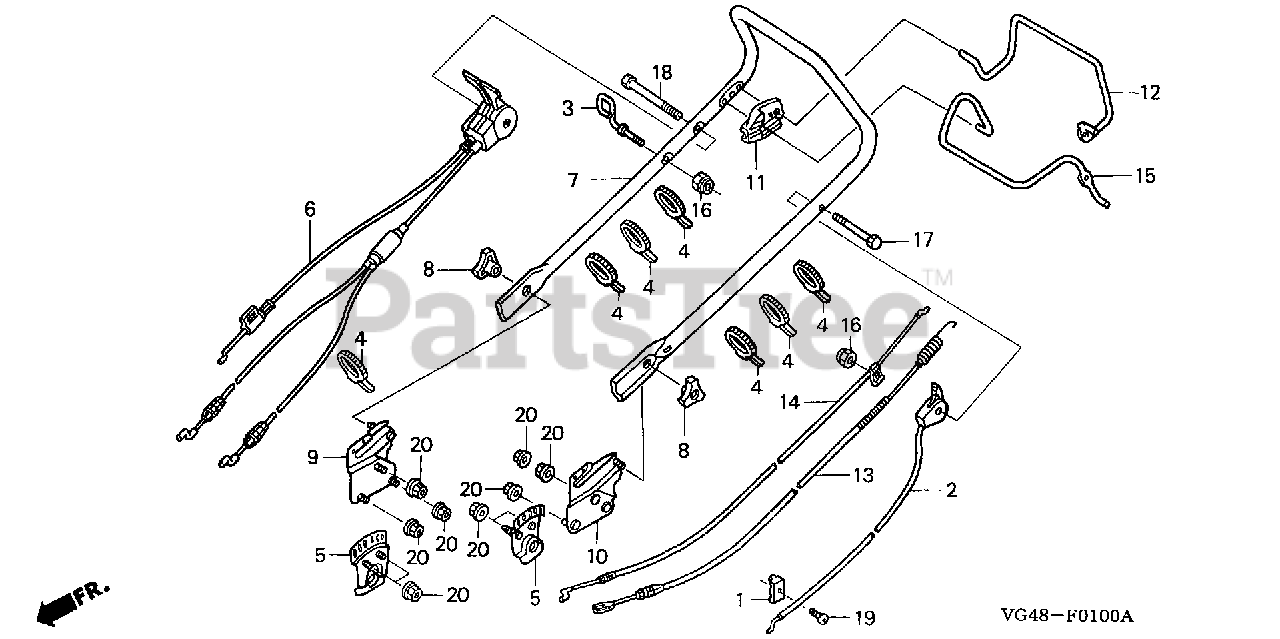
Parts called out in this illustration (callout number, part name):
1	HOLDER, CABLE
2	LEVER ASSY., THROTTLE
3	GUIDE, ROPE
4	TIE, CABLE (157.5MM)
5	PANEL, RR. ADJUSTER
6	CABLE, CASTER
7	PIPE, HANDLE *NH105* (MAT BLACK)
8	GRIP, HANDLE JOINT
9	STAY, R. HANDLE
10	STAY, L. HANDLE
11	STOPPER, LEVER
12	LEVER, CLUTCH
13	CABLE, CLUTCH
14	CABLE, BRAKE
15	LEVER, BRAKE
16	NUT, NYLON LOCK (6MM)
17	BOLT, HEX. (6X60)
18	BOLT, HEX. (6X80)
19	SCREW, PAN (5X16)
20	NUT, FLANGE (8MM)
